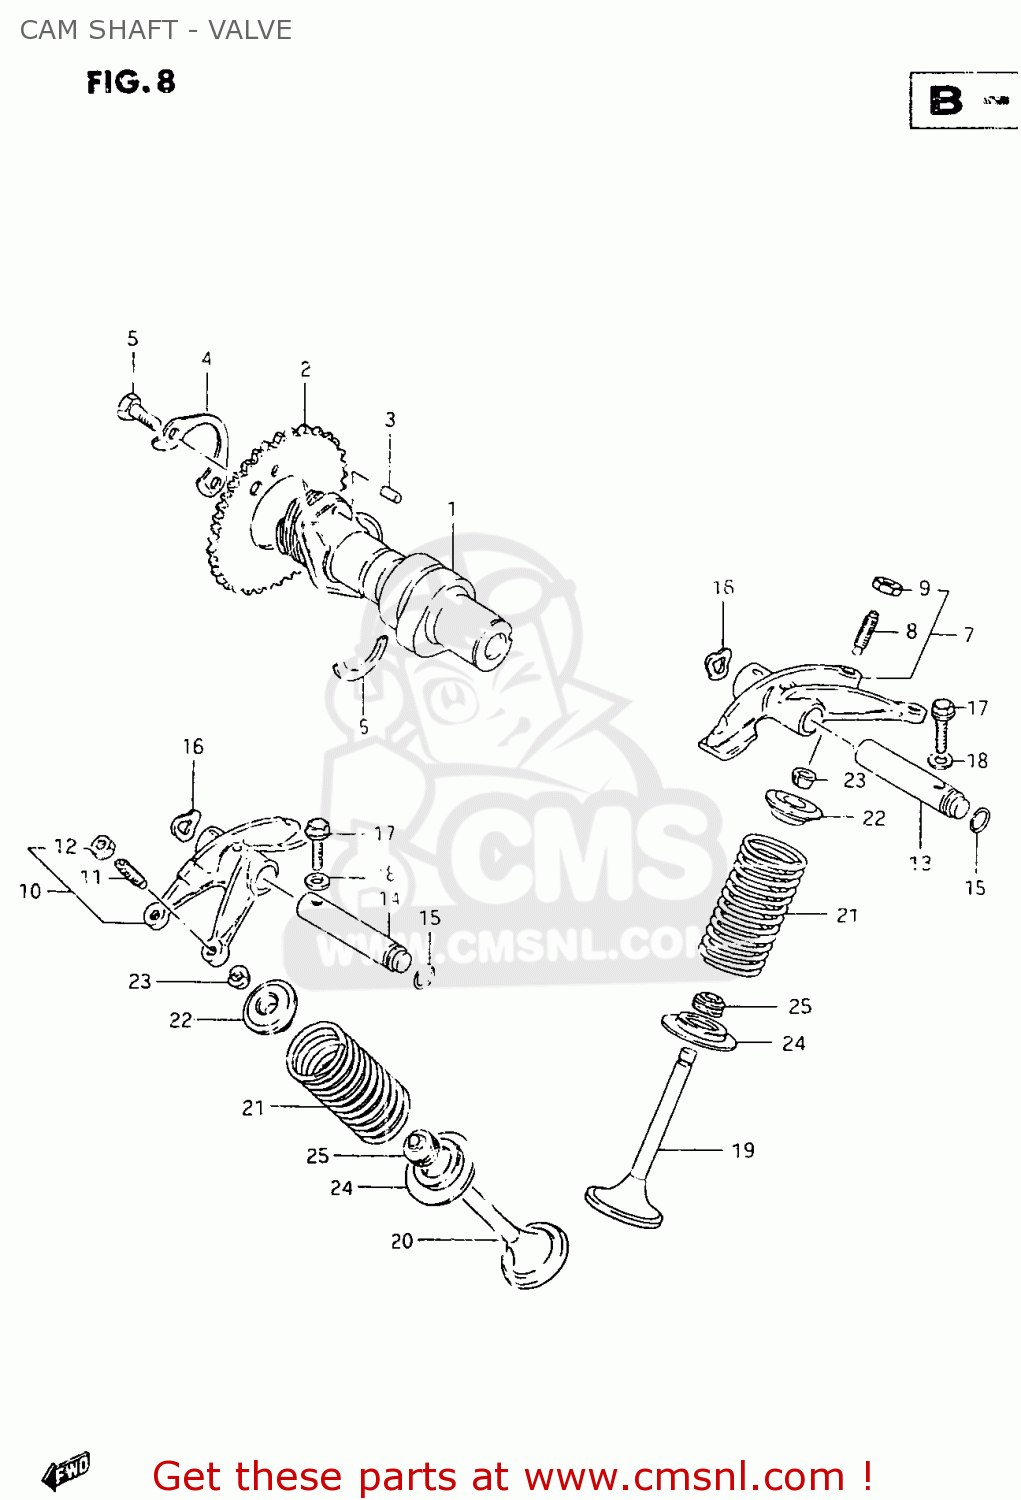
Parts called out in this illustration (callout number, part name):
1	CAMSHAFT
2	SPROCKET,CAMSHAFT(NT:42)
3	PIN
4	WASHER,CAM CHAIN SPROCKET
5	BOLT(6X12.5)
6	C RING
7	ARM,VALVE ROCKER INTAKE
8	SCREW,TAPPET ADJUSTING
9	NUT,TAPPET ADJUSTING
10	ARM,VALVE ROCKER EXHAUST
11	SCREW,TAPPET ADJUSTING
12	NUT,TAPPET ADJUSTING
13	SHAFT,VLV ROCKER ARM IN(L:91.5
14	SHAFT,VLV ROCKER ARM EXH(L:76)
15	O RING(D:1.9,ID:8.6)
16	WASHER
17	BOLT
18	GASKET(5.8X13X1.2) (NAS)
19	VALVE,INTAKE
20	VALVE,EXHAUST
21	SPRING,VALVE
22	RETAINER,VALVE SPRING
23	COTTER VALVE
24	SEAT,VALVE SPRING
25	SEAL,OIL(5.5X11X8.2)
